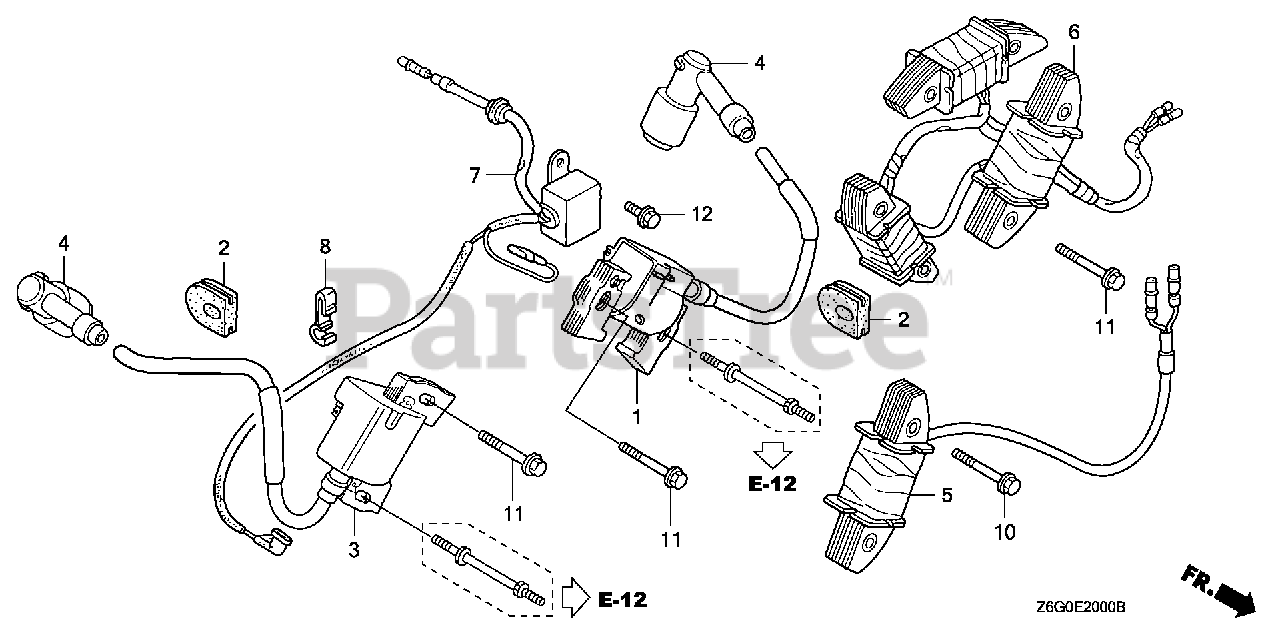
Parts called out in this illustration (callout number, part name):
1	COIL ASSY., IGNITION (200MM) (BLACK) (L. SIDE)
2	GROMMET, IGNITION WIRE
3	COIL ASSY., IGNITION (215MM) (GRAY) (L. SIDE)
4	CAP ASSY., NOISE SUPPRESSOR
6	COIL ASSY., CHARGE (12V/20A)
7	DIODE ASSY., ENGINE STOP
8	CLAMP, WIRE
11	BOLT, FLANGE (6X32)
12	BOLT, FLANGE (6X8)
